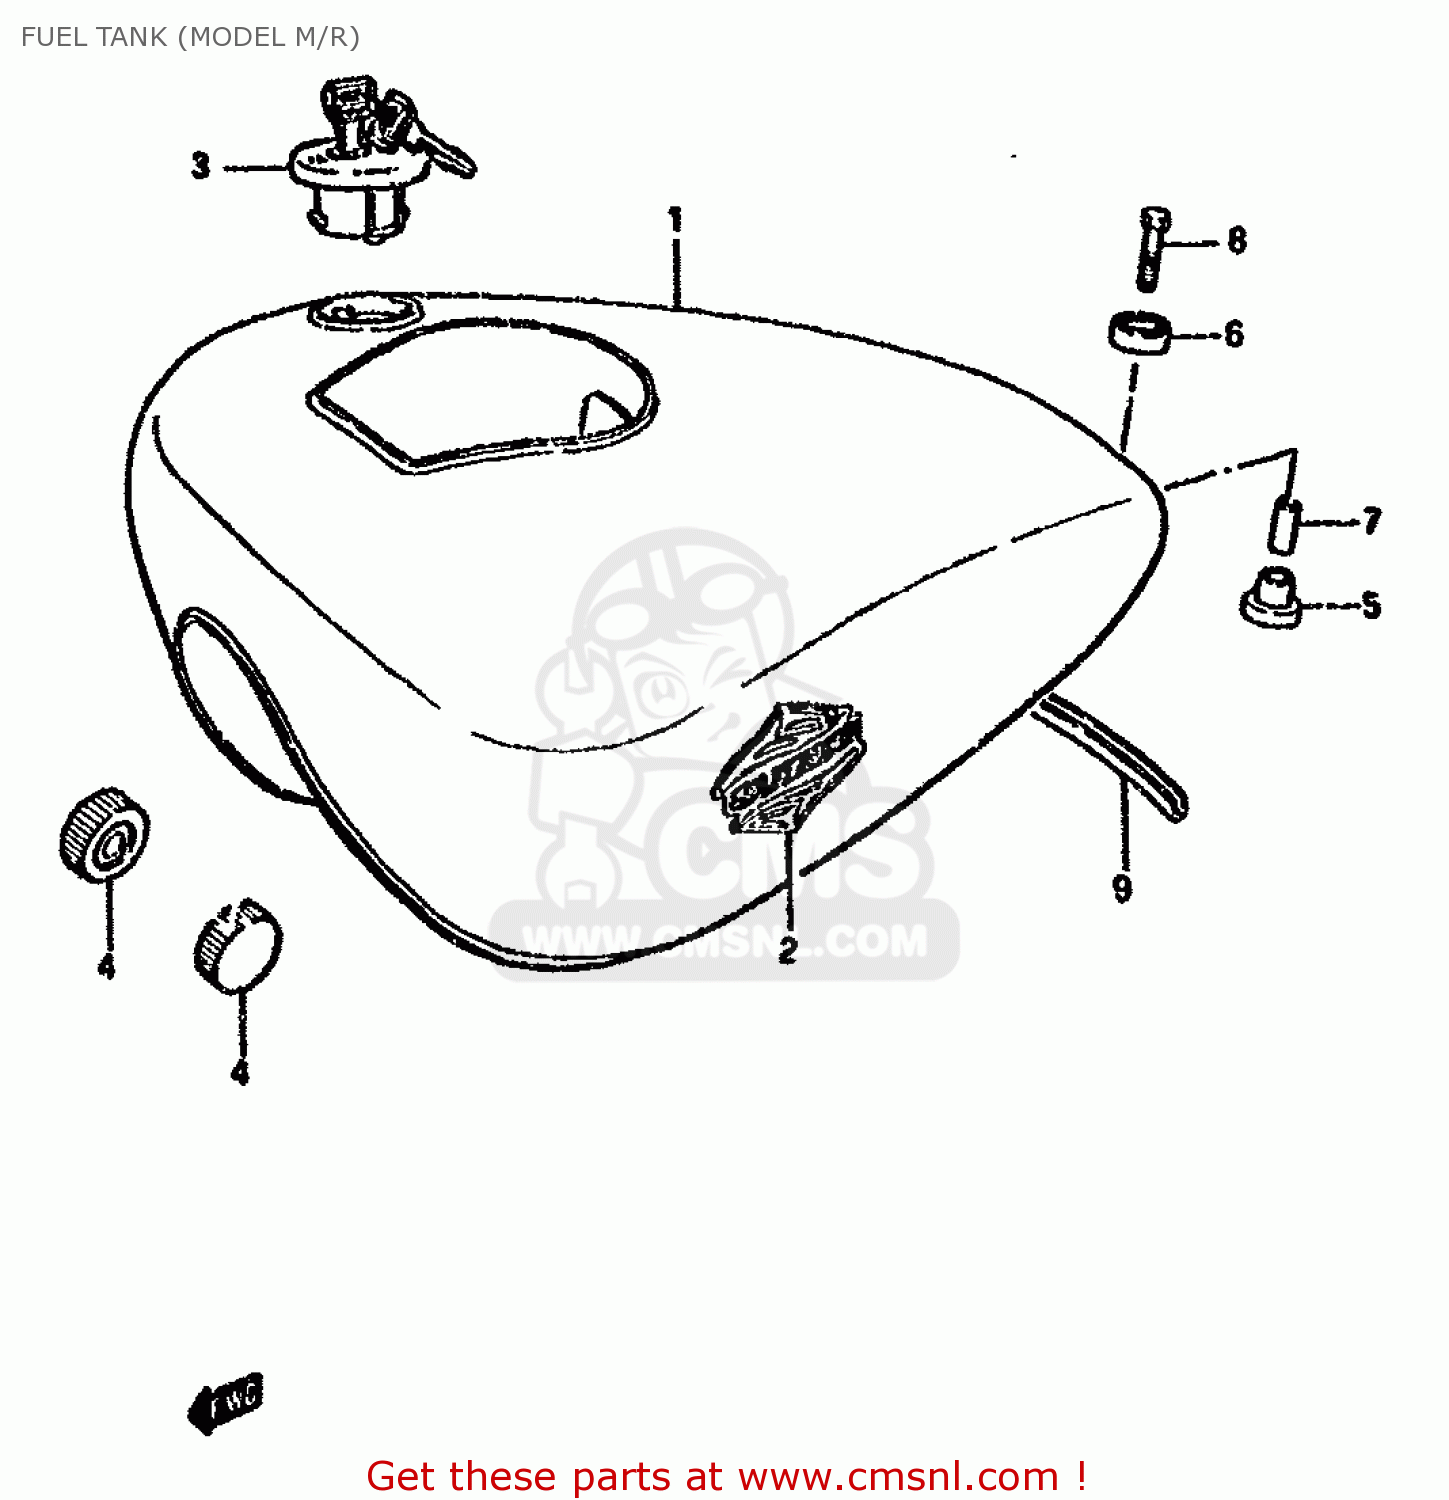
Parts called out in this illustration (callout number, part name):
1	TANK ASSY,FUEL
2	EMBLEM,FUEL TANK
3	CAP SET,FUEL TANK
4	CUSHION
5	CUSHION
6	CUSHION
7	SPACER
8	BOLT
9	MOLDING,FUEL TANK RR
12	LABEL,FUEL CAUTION
